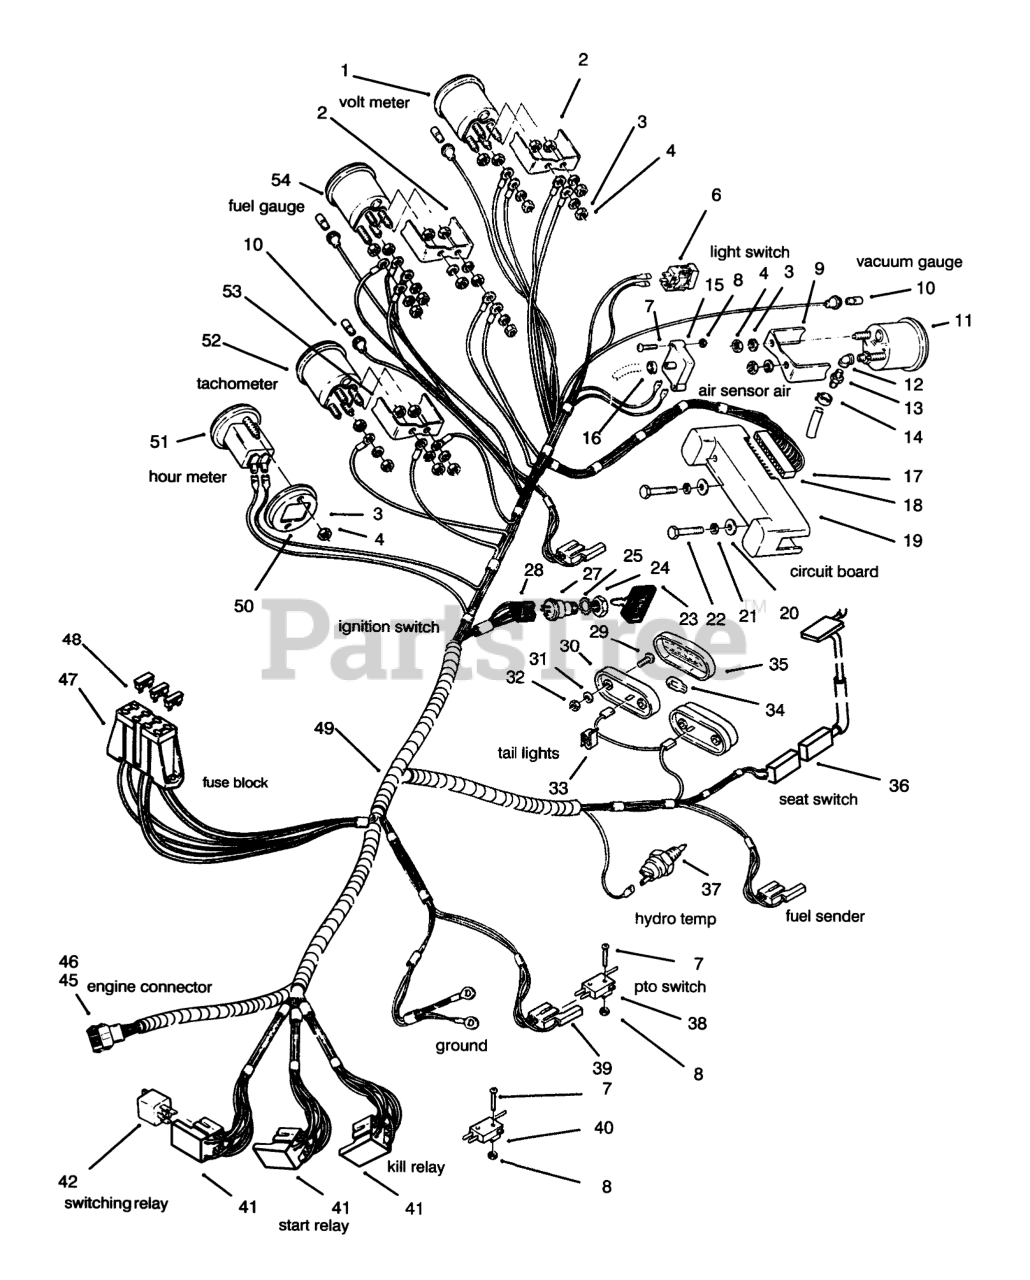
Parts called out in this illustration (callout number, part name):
1	Voltmeter (Incl. Ref. #2-4)
2	CLAMP-MOUNTING
3	WASHER-LOCK
4	NUT-HEX
6	SWITCH-HEADLIGHT
7	Screw
8	NUT-HEX
9	Bracket-Mounting
10	LAMP-MINIATURE GE 53X
11	Gauge-Vacuum (Incl. Ref. #3-4 & 9)
12	ELBOW
13	FITTING STRAIGHT
14	Clamp
15	SENSOR-AIR CLEANER
16	CLAMP-HOSE 5/16"
17	Terminal
18	Connector-Male
19	CIRCUIT-BRD 8 LIGHT
20	WASHER-FLAT
21	WASHER-LOCK
22	Screw
23	KEY-IGNITION
25	WASHER-LOCK
27	Switch-Ignition (Incl. Ref. #24-25)
28	CONNECTOR-5 WAY-SERV
29	SCREW-PPH
30	BASE-TAIL LIGHT
31	WASHER-LOCK, INT
32	NUT-LOCK, NI
33	SPEED CLIP
34	LIGHT BULB
35	LENS-TAIL LIGHT
36	SWITCH-SEAT
37	SENSOR-HYDRO OIL HOT
38	SWITCH
39	CONNECTOR BODY
40	SWITCH - CLUTCH
41	Connector-Relay
42	RELAY
47	FUSE-HOLDER 4 WAY
48	FUSE-10 AMP
49	WIRING-HARNESS & DIA
50	CLAMP-HOUR METER
51	Hourmeter (Incl. Ref. #3-4 & 49)
52	Tachometer (Incl. Ref. #1, 3-4 & 52)
53	BRACKET - GAUGE MOUNT
54	Gauge-Fuel (Incl. Ref. #2-4)
